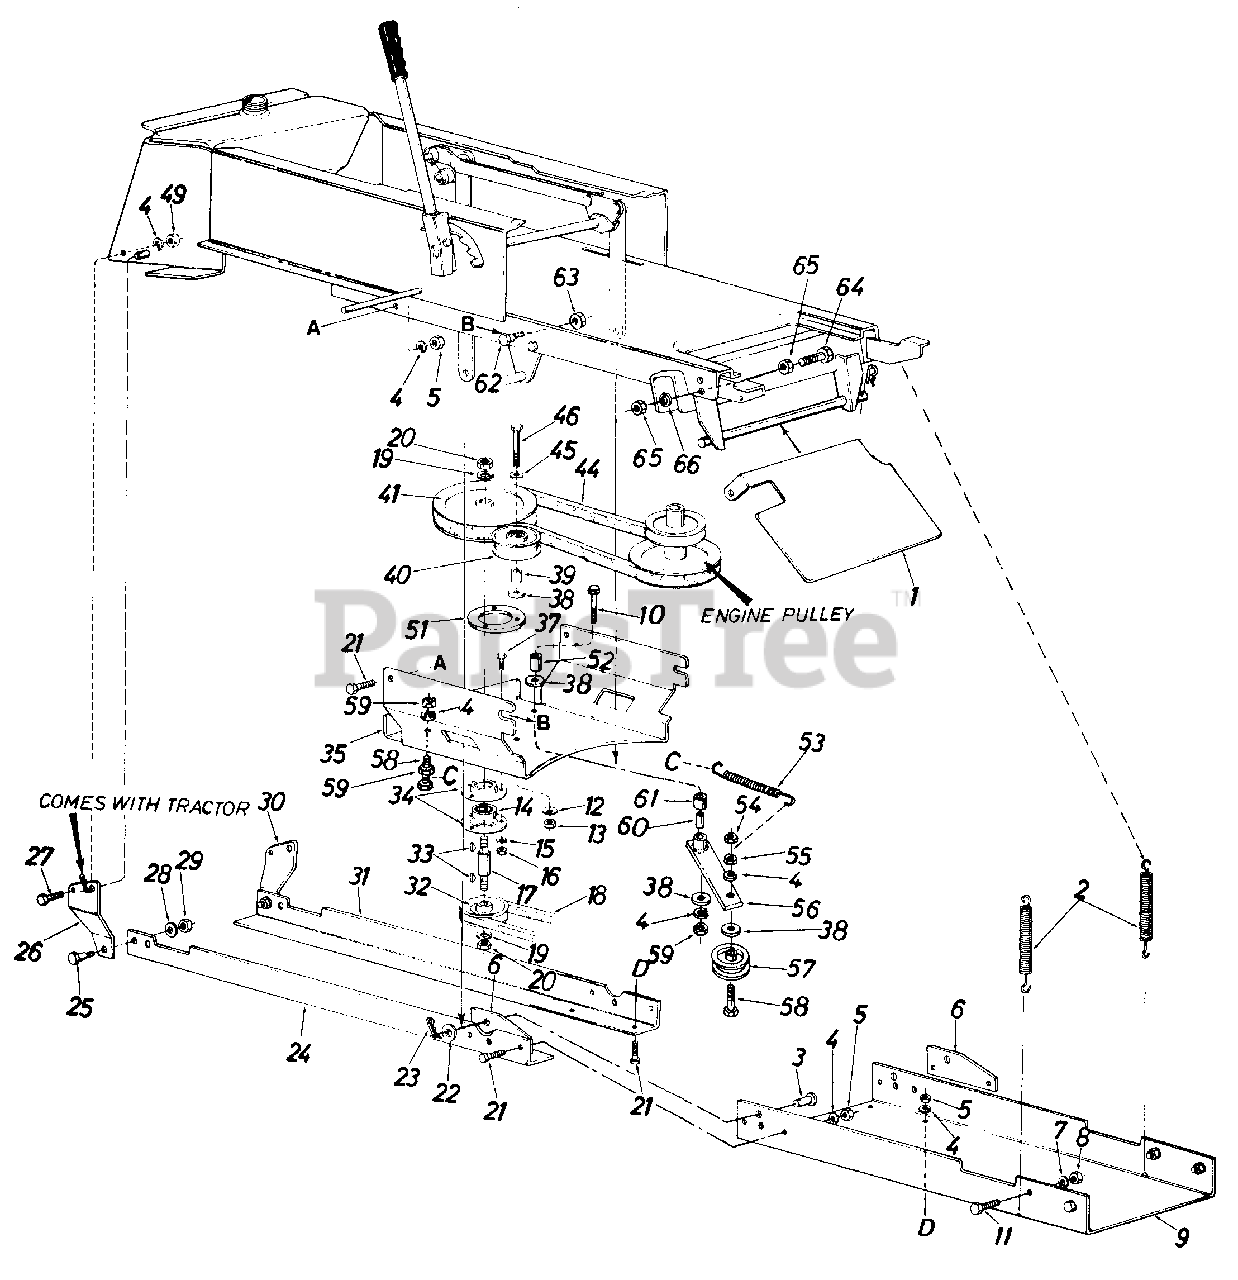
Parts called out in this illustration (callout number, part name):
1	Guide Bracket
2	Helper Spring
3	Clevis Pin
4	L.-Wash. 3/8" I.D.*
5	Hex L.-Nut 3/8-24 Thd.
6	Attaching Plate
7	L.-Wash. 1/2" I.D.*
8	Hex L.-Nut 1/2-20Thd.
9	Front Support Channel
10	Hex Bolt 3/8-16 x 3.75" Lg.
11	Hex Bolt 1/2-20 x 1.25" Lg.*
12	Belleville Wash. 3/8" I.D.
13	Hex L.-Nut 3/8-16 Thd.
14	Ball Bearing
15	L.-Wash. 5/16" I.D.*
16	Hex Nut 5/16-18 Thd.*
17	Spindle
18	V-Belt 1/2" x 88" x 2 (Kevlar)
19	L.-Wash. 5/8" I.D.*
20	Hex Jam Nut 5/8- 11 Thd.
21	Hex Bolt 3/8-24 x 1.00" Lg.*
22	Flat Washer
23	Internal Cotter Pin
26	Rear Hanger Brkt.-R.H.
27	Hex Bolt 3/8 x 1.00" Lg.*
28	Fl.-Wash. .44" I.D. x 1.38" O.D. x .130
29	Hex L.-Nut 7/16-24Thd.
30	Rear Hanger Brkt.-L.H.
31	Rear Support Angle-L.H.
32	Lower Drive Pulley 5/8 x 5.56
33	#6 Hi-Pro Key 3/16 x 5/8" Dia.
34	Bearing Housing
35	Supporting Bracket
37	Hex Sems Bolt 5/16-18 x 1.00" Lg. *
38	Fl.-Wash. .38" I.D. x 1.00" O.D. x .135
39	Spacer .38" I.D. x .62" O.D.
40	Fl.-Idler Pulley
41	Upper Drive Pulley
44	V-Belt 1/2" x 49.8" Lg.
45	Fl.-Wash.
46	Hex Bolt 3/8-16 x 2.50" Lg.*
49	Hex Nut 3/8-16 Thd.*
53	Extension Spring .54" O.D. x 4.75" Lg.
54	Hex Cent. L.-Nut 3/8-16 Thd.
55	Hex Jam Nut 5/8-11 Thd.
56	Idler Arm Ass'y.
57	Idler Pulley
58	Hex Bolt 3/8-16 x 2.25" Lg.
59	Hex Jam Nut 3/8-16 Thd.
60	Spacer .377" I.D. x .60" O.D. x .830" Lg.
61	Spacer.380" I.D. x .630" O.D. x .565" Lg.
62	Shoulder Bolt.498 Dia, x .340
63	Hex Cent. L.-Nut 3/8-16 Thd.
64	Hex Bolt 1/4-28 x 1.5" Lg.*
65	Hex Nut 1/4-28 Thd.*
66	L.-Wash. 1/4" I.D.*
